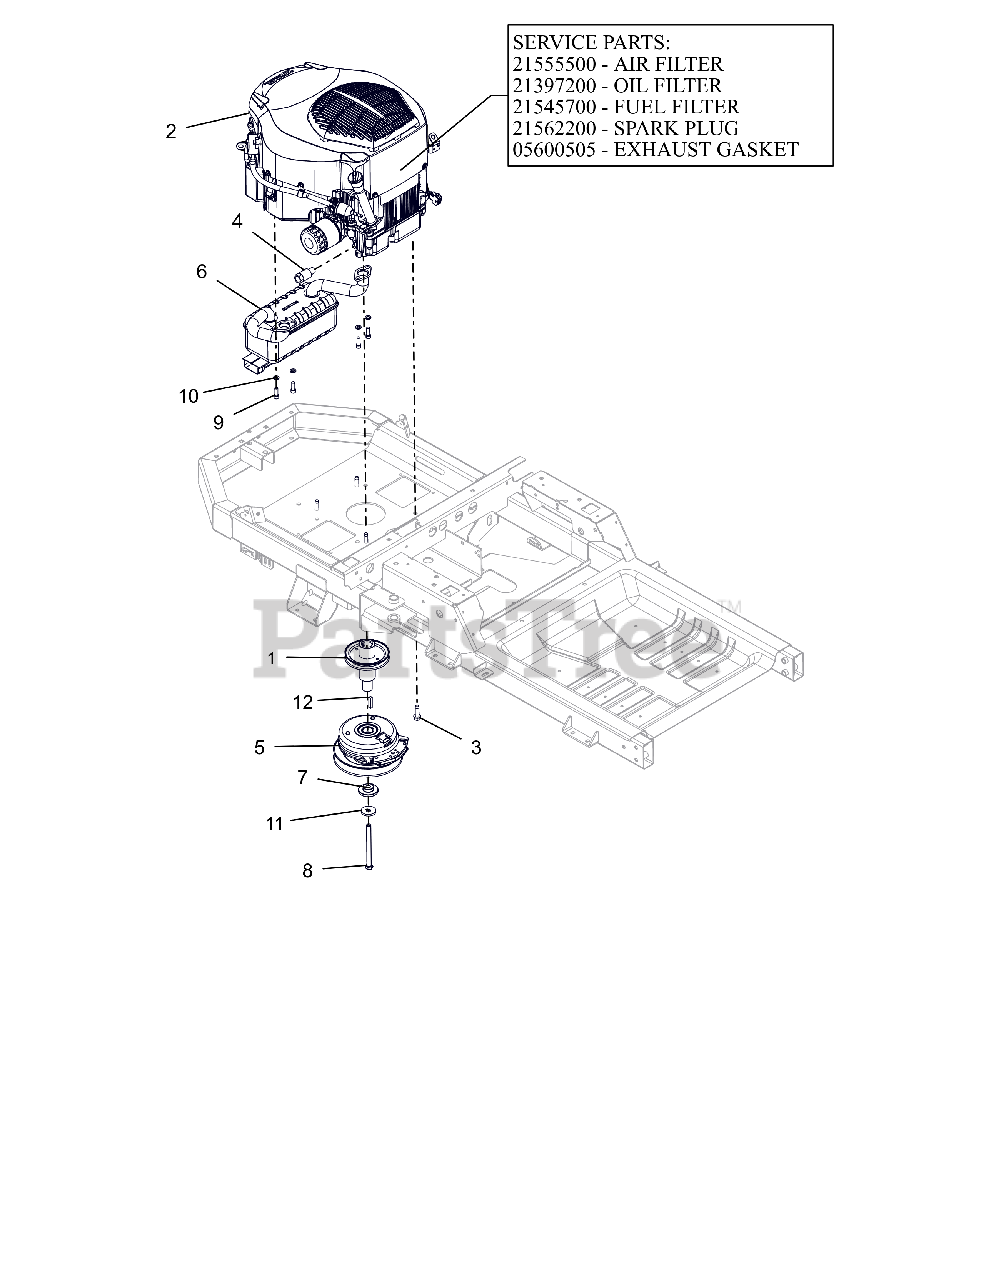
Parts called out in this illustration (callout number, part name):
1	WLDMT, DRIVE SHEAVE (LG XL)CZC
2	ENGINE, KOHLER 24HP TWIN
2	AIR CLEANER, KOHLER
2	FILTER, OIL - KOH CV20
2	FILTER-FUEL KOHLER COURAGE PRO
2	PLUG, SPARK (RFI)
2	GASKET, MUFFLER COURAGE TWIN
3	SCR,TAP .375-16X1.25HWH TR ZCC
4	DRAIN, OIL
5	CLUTCH,105FTLB MONOPOLE 6.83"
6	MUFFLER, KOHLER
7	BSHG-FLG .469X1.06X.574X2.0
8	BLT-HEX.438-20X5 GR8 YZ NYTORQ
9	SCR-CAP .31-18X.88 S/HD G8 ZCC
10	WSHR,LK-REG .312X.078 ZCC
11	WASHER, 7/16" SPRING DISK
12	KEY-SQ .25 X 1.25 X .25 SAE
